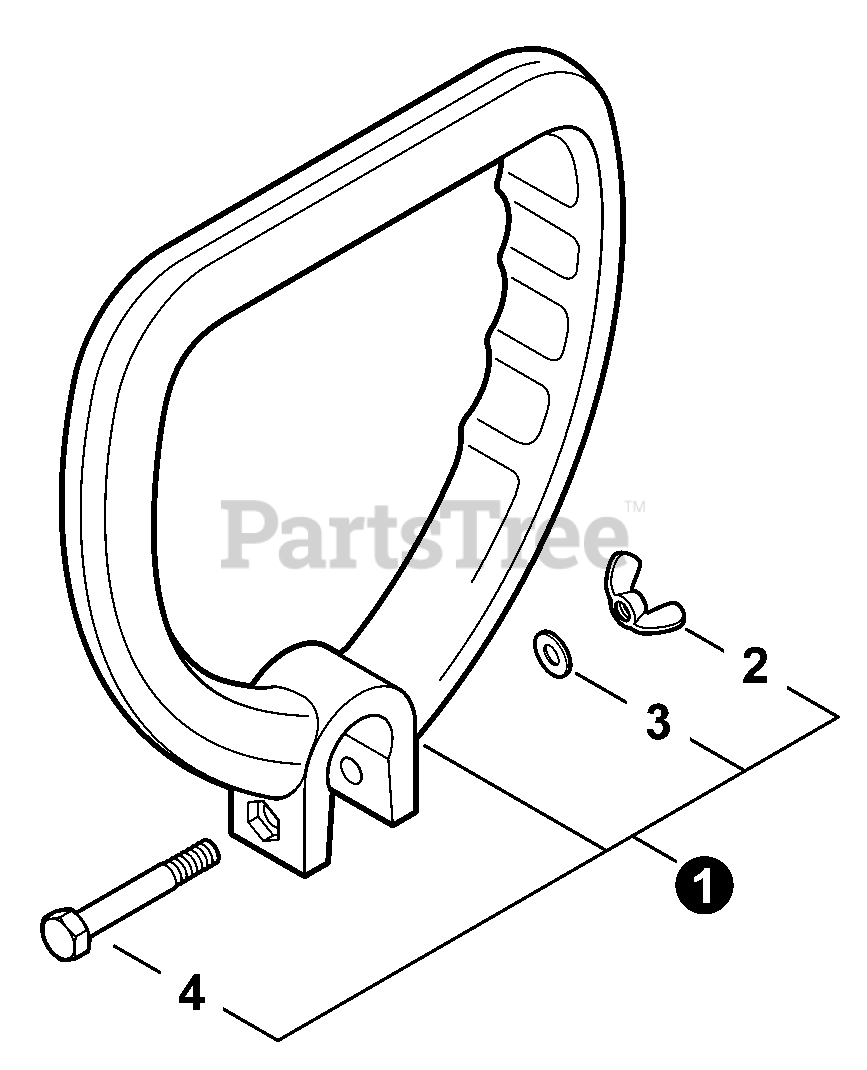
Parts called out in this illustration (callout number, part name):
1	HANDLE ASSY
2	NUT, WING 1/4"-20
3	WASHER, 1/4"
4	BOLT 1/4"-20x1-3/4"
